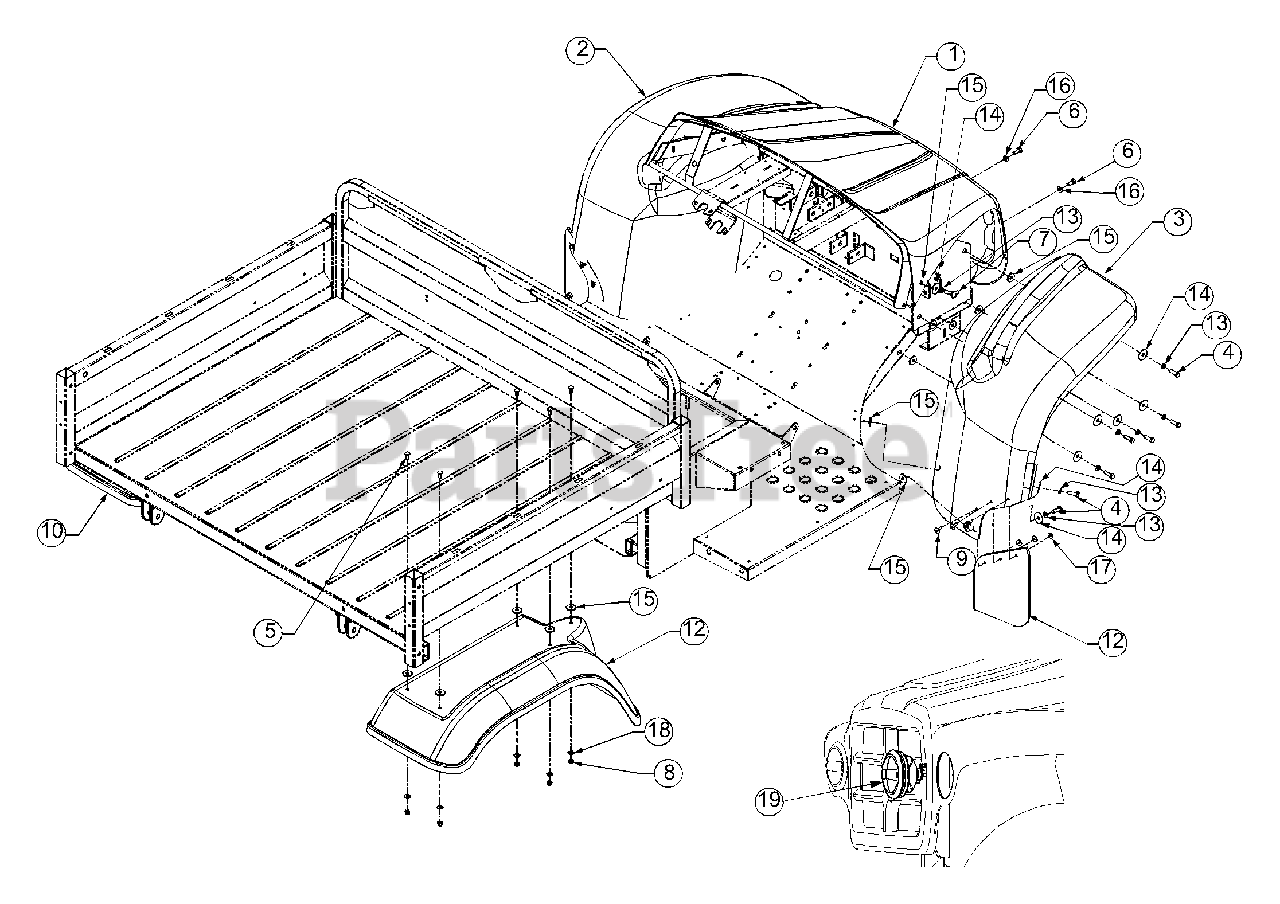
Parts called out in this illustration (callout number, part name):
1	Panel, Hood
2	Panel, Front Fender, LH
3	Panel, Front Fender, RH
4	Hex Screw, 5/16-18 x 1.0 Gr5
5	Hex Screw, 1/4-20 x .75
6	Hex Screw, 5/16-18 x .75 Gr5
7	Screw, Thumb 5/16-18
8	Hex Lock Nut, Nylon, 1/4-20
9	Rivet, Pop
10	Panel, Rear Fender, LH
13	Lock Washer, 5/16
14	Flat Washer, .350 x 1.25 x .06
15	Washer, Rubber, .310 x 1.0 x .125
16	Flat Washer, .44 x .688 x .65
17	Flat Washer, .194 x .62 x .063
18	Flat Washer, .271 x .630 x .065
19	Headlight Assembly
